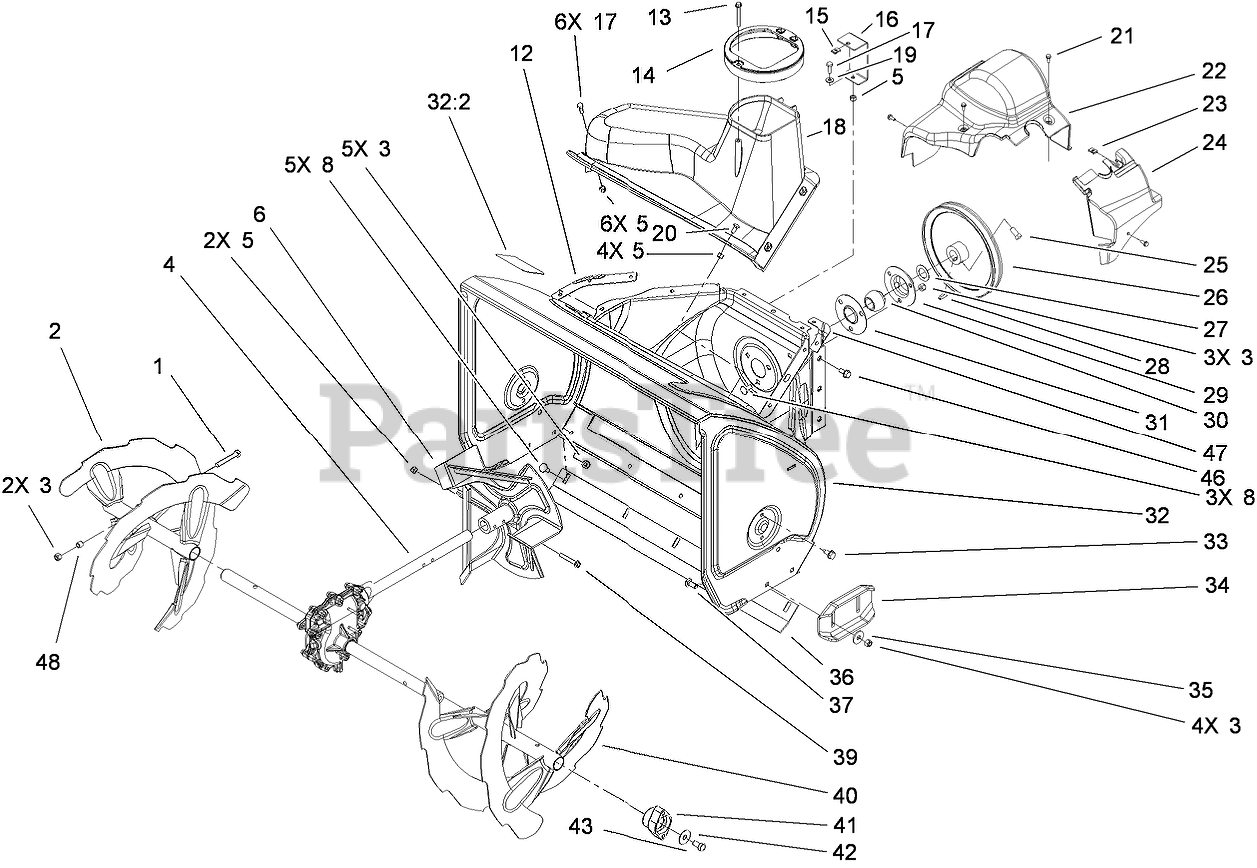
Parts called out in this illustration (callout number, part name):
1	SCREW-HH
2	RH AUGER ASM
3	NUT-LOCK, NI
4	28 INCH AUGER GEARCASE ASM
5	NUT-LOCK, NI
6	IMPELLER ASM
8	SCREW-CARR
12	SEAL-FLANGE, COVER
13	SCREW-PLASTITE
14	GUIDE-CHUTE
15	NUT-SPEED, U-TYPE
16	BRACKET-COVER, CLIP NUT
17	SCREW-HH
19	WASHER-FLAT
20	BOLT-CARR
21	SCREW-HWH
22	COVER-BELT
23	NUT-SPEED
24	COVER-EXTENSION, BELT
25	SCREW-SET, SQH
26	PULLEY-IMPELLER
27	WASHER-THRUST
28	KEY-WOODRUFF
29	FLANGE-CUP, BEARING
30	BEARING-BALL
31	FLANGE-CUP, BEARING
32	HOUSING-AUGER, 28 INCH
32:2	DECAL-WARNING, AUGER
33	SCREW-HWHTF
35	WASHER
36	SCRAPER-FIXED
37	SCREW-CARR
39	SCREW-HHF
40	LH AUGER ASM
41	BEARING-AUGER
42	WASHER
43	SCREW-HH
46	SCREW-HWHTF
48	SPACER
